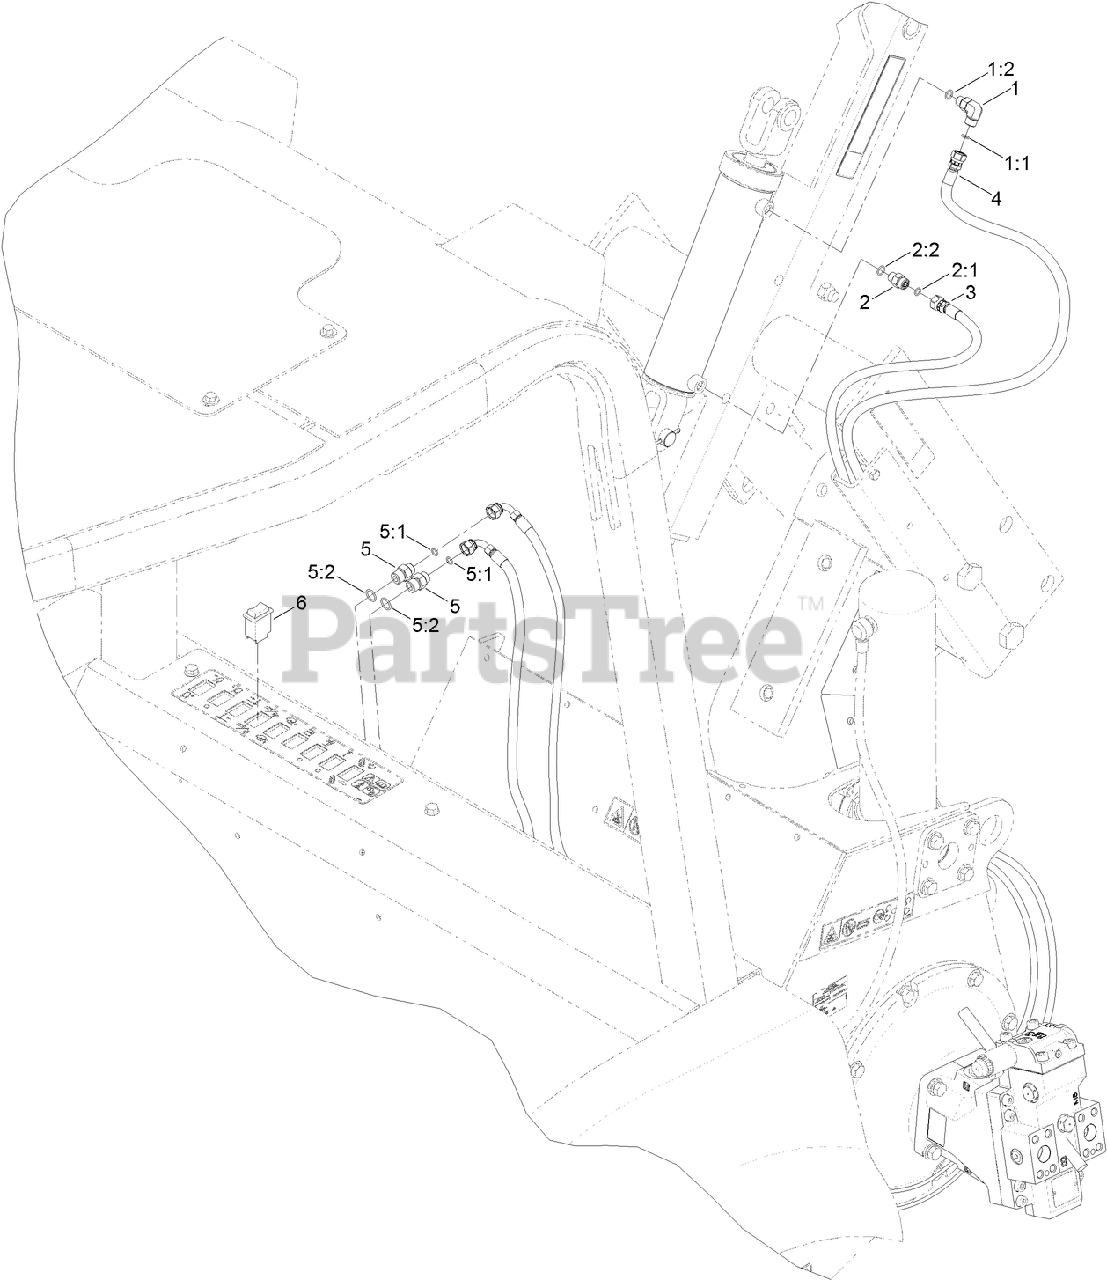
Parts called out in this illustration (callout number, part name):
1	FITTING-ELBOW, 90 DEG
1:1	O-RING
1:2	O-RING
2	FITTING-STRAIGHT
2:1	O-RING
2:2	O-RING
3	HOSE ASM-HYD HP
4	HOSE ASM-HYD HP
5	FITTING-STRAIGHT
5:1	O-RING
5:2	O-RING
6	SWITCH-ROCKER, 2 POLE
